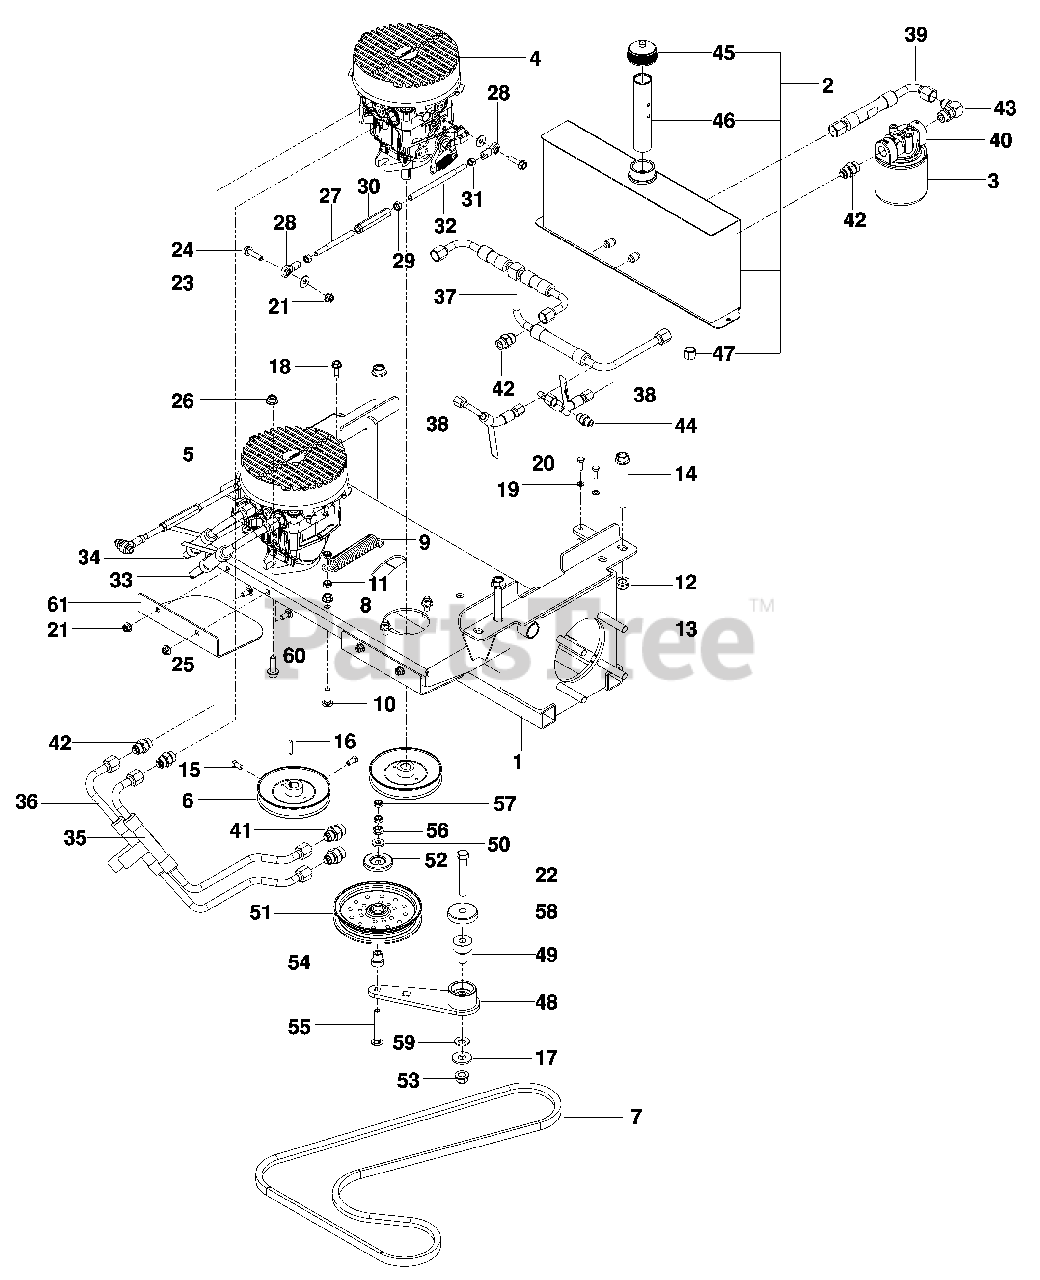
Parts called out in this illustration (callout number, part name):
1	FRAME, SUB
2	OIL TANK ASSY
3	FILTER, 25 MICRON
4	PUMP, 16CC RT
5	PUMP, 16CC LT
6	PULLEY, PUMP, 17MM
8	NUT 3/8-16 HEX WHIZLK
9	SPRING, PUMP
10	BOLT 3/8-16 x 1¼ RD HD
11	NUT 3/8-16 HEX JAM NYLOC
12	NUT ½-13 HEX FLG NYLOC
13	BOLT ½-13 x 2¾ HEX NYLOC
14	BOLT ½-13 x 4 HEX FLG
15	SCREW 5/16-18 x 5/8 SET
16	KEY, METRIC
17	WASHER ½ FLAT
18	BOLT 5/16-18 x 1 THD FRM
19	WASHER ¼ SPLIT LOCK
20	BOLT ¼-20 x ¾ HEX NYLOC
21	NUT 5/16-18 HEX FLG NYLOC
22	BOLT ½-13 x 3¼ HEX NYLOC
23	WASHER 5/16 STD FLT
24	SCREW 5/16-18 x 1¼ TPBLT
25	SCREW 3/8-16 x 1¼ HEX FLG
26	NUT 3/8-16 HEX FLG NYLOC
27	LINKAGE, CONTROL, FT
28	BALL END, RT
29	NUT 3/8-24 HEX JAM
30	TURNBUCKLE 3/8
31	NUT 5/16-24 HEX
32	LINKAGE, CONTROL, RR
33	LINE, HYDRAULIC, RT-A
34	LINE, HYDRAULIC, RT-B
35	LINE, HYDRAULIC, LT-A
36	LINE, HYDRAULIC, LT-B
37	LINE, HYDRAULIC, CHARGE
38	LINE, HYDRAULIC, CASE
39	LINE, HYDRAULIC, SUCTION
40	FILTER HEAD
41	STRAIGHT CONNECTOR
42	STRAIGHT CONNECTOR
43	ELBOW 90O ADJ
45	CAP, HYDRAULIC
46	TUBE, ANTI-SPLASH
48	ARM, IDLER, w/ BEARINGS
49	PIVOT, BEARING
50	WASHER 3/8 THICK
51	IDLER PULLEY
52	SHIELD, DUST
53	NUT ½-13 HEX FLG NYLOC
54	PIVOT, IDLER
55	BOLT 3/8-16 x 2¾ RD HD
56	NUT 3/8-16 HEX WHIZLK
57	NUT 3/8-16 HEX JAM NYLOC
58	SHIELD, DUST
59	WASHER ½" BELLEVILLE
60	BOLT 5/16-18 x ¾ RD HD
61	SHIELD, PULLEY
